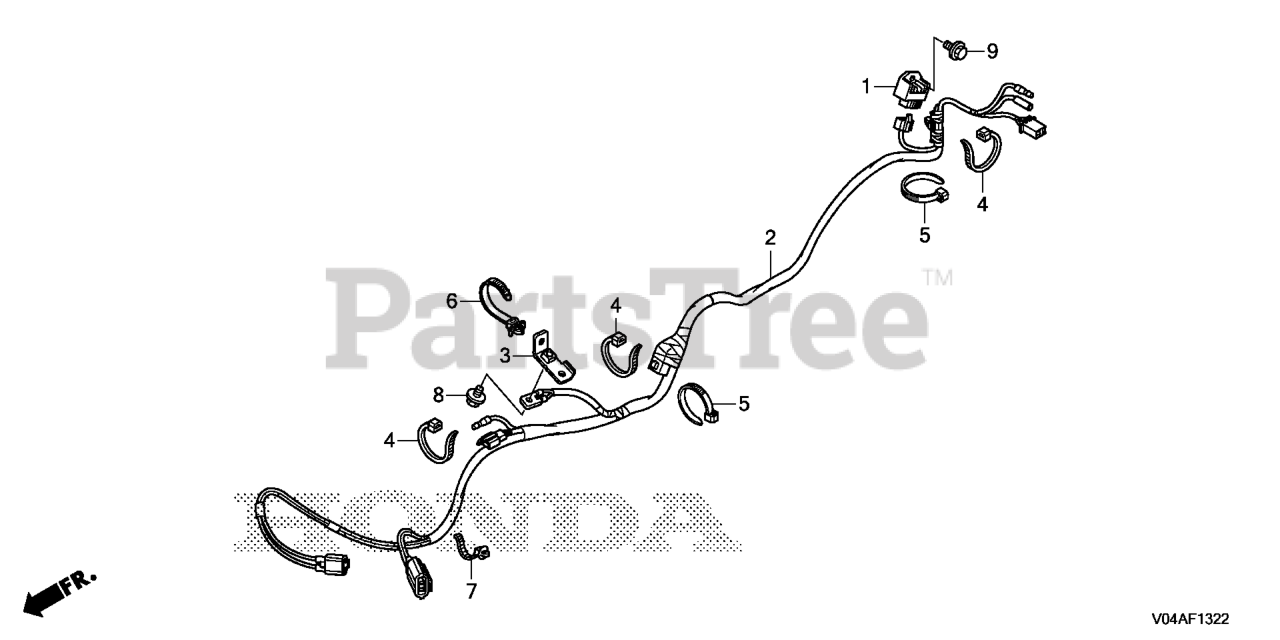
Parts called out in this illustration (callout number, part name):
2	WIRE HARNESS ASSY., MAIN
3	BRACKET, WIRE HARNESS CLIP
4	BAND, WIRE (95MM)
5	BAND, WIRE (165MM) (BLACK)
6	STRAP, CABLE (118MM) *NH1L* (Honda Code 1170653). (BLACK)
7	CLIP, HARNESS BAND (145MM) (BLACK)
8	BOLT, FLANGE (6X10)
9	BOLT, FLANGE (6X12) Use up to Engine SN 1543277.
